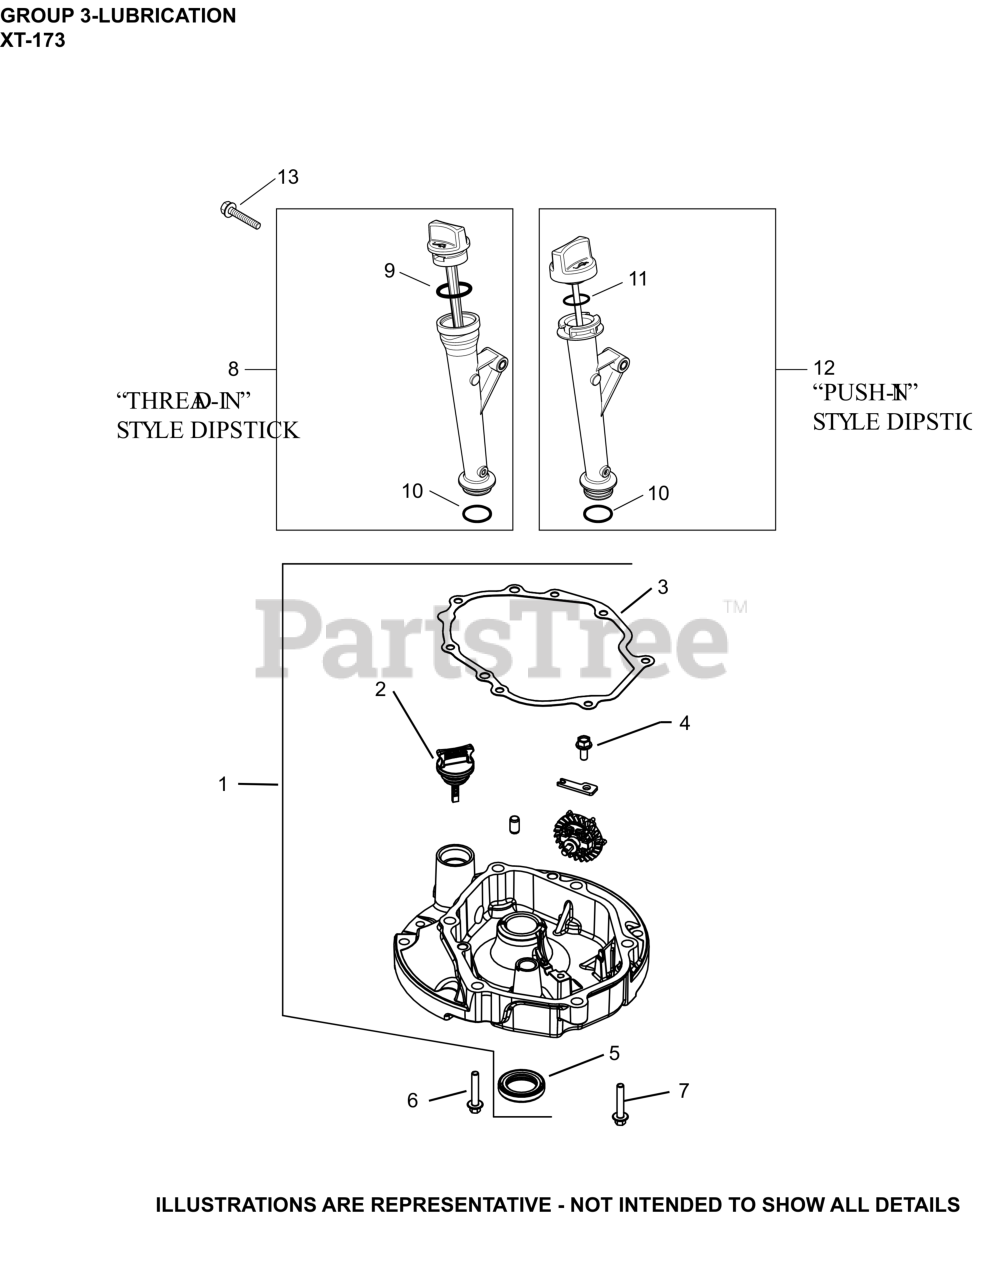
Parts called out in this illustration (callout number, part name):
1	KIT, OIL PAN
3	GASKET, OIL PAN
5	SEAL, OIL (PTO)
6	SCREW, HEX FLANGE (M8)-USE 25 086 456-S
7	SCREW, HEX FLANGE (M6)-(#25086435S)
10	O-RING, OIL FILL TUBE
11	O-RING (CAP)
12	KIT, DIPSTICK AND TUBE-(#1412320S)
NI	TUBE ASSEMBLY, OIL FILL
NI	PLUG, PIPE (W/SEALANT)
NI	CAP, DIPSTICK ASSEMBLY
NI	GEAR ASSEMBLY, GOVERNOR
